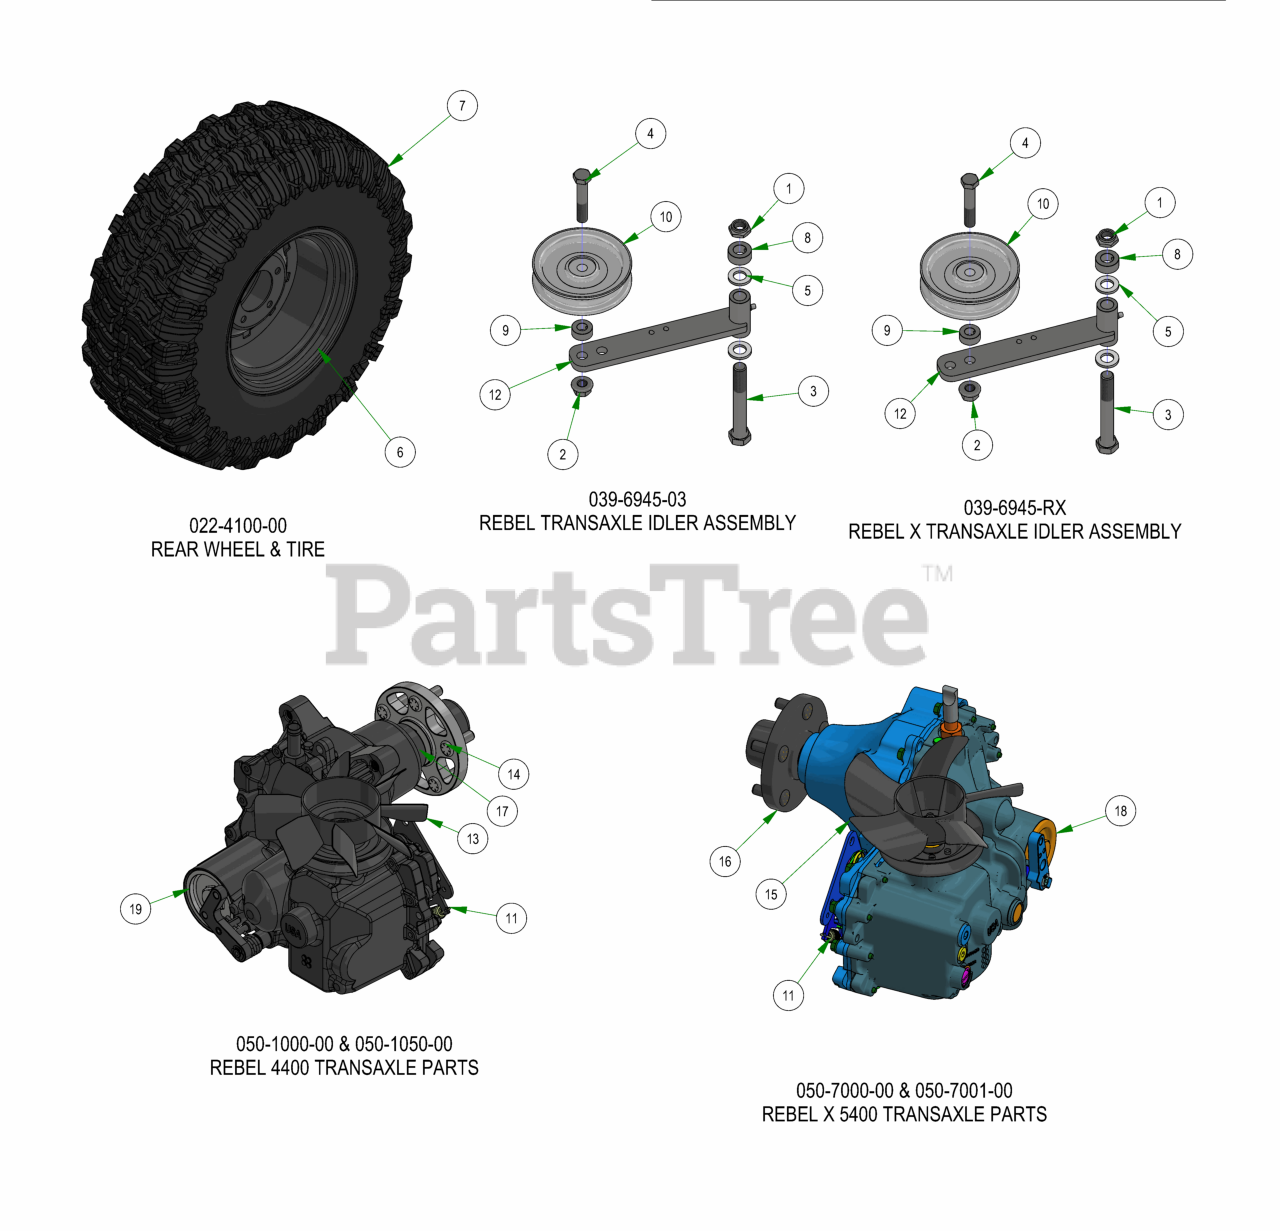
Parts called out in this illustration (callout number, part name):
1	5/8-11 NYLON INSERT JAM LOCKNUT ZINC
2	1/2-13 NYLON INSERT FLANGE LOCKNUT ZINC
3	5/8-11 X 4-1/2 HEX CAP SCREW (GR.5) ZINC
4	1/2-13 X 2-3/4 HEX CAP SCREW (GR.5) ZINC
5	.635 ID X 1.120 OD X .140 THICK FLAT WASHER NYLON
6	12x12" Black Wheel For 2015 Outlaw
7	24x12-12 Reaper Turf Tire
8	5/8 SOLID SHAFT COLLAR (W/1 SET SCREW) ZINC
9	1/2 SOLID SHAFT COLLAR (W/1 SET SCREW) ZINC
10	4 3/4" Idler Pulley
11	Gold Transaxle Spring
12	Deck Idler
13	Fan/Pulley Kit for 4400 Outlaw
14	Transaxle Wheel Studs/ Drum Brake Studs
15	FAN/PULLEY KIT
16	5 BOLT HUB KIT
17	Seal Kit for 4400 Series Outlaw Transaxle
18	FILTER FOR 5400 TRANSAXLE
19	Hydro Filter for 4400 Transaxle
